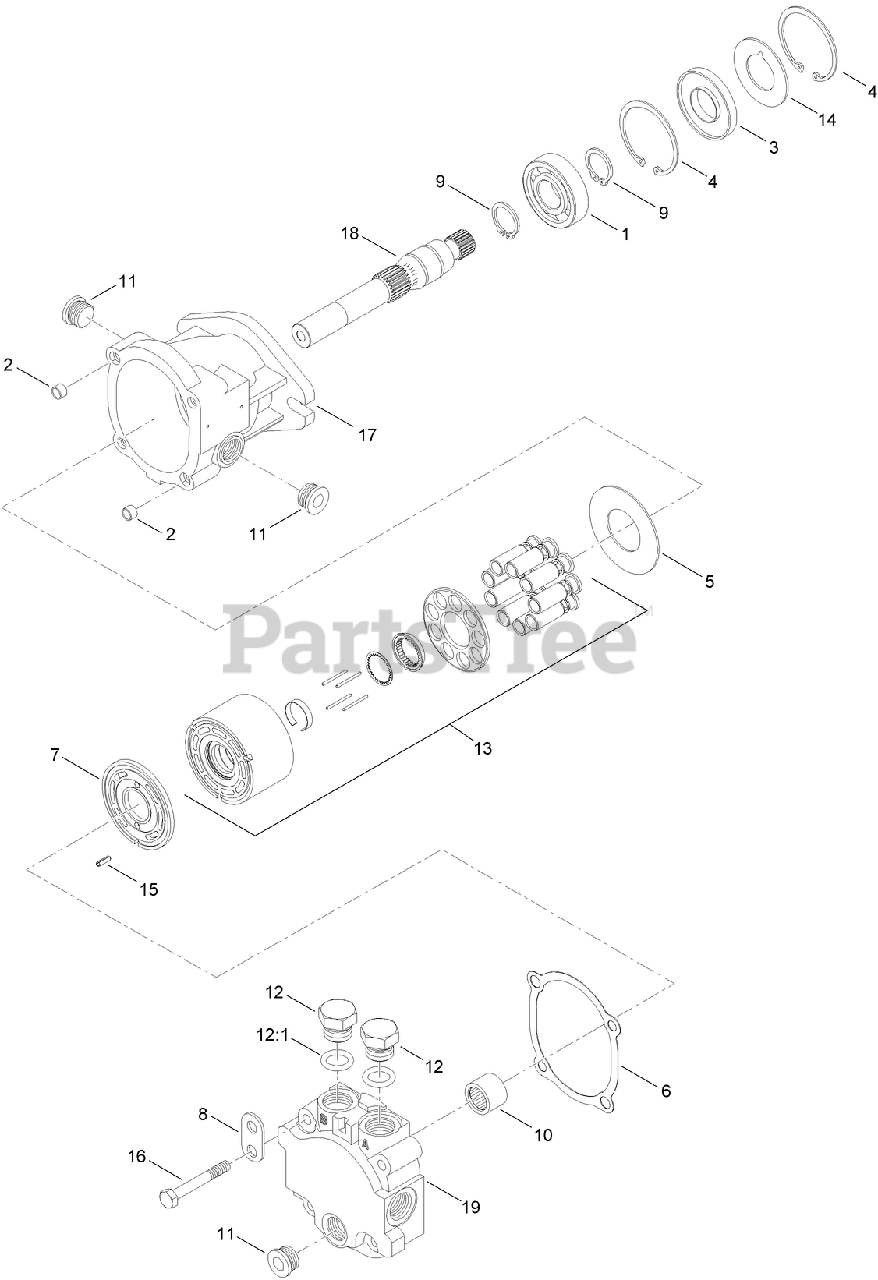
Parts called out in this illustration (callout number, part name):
1	BEARING
2	PIN-Spring
3	SEAL-LIP
4	RING-RETAINING
5	PLATE-Thrust
6	GASKET-End Cap
7	PLATE-Valve
8	BRACKET-Lifting
9	RING-RETAINING
10	BEARING-Needle
11	PLUG-PIPE
12:1	O-RING
13	CYLINDER BLOCK KIT
14	WASHER-BACKUP
15	PIN-SLOTTED
16	SCREW-HH
17	HOUSING
19	CAP-End
